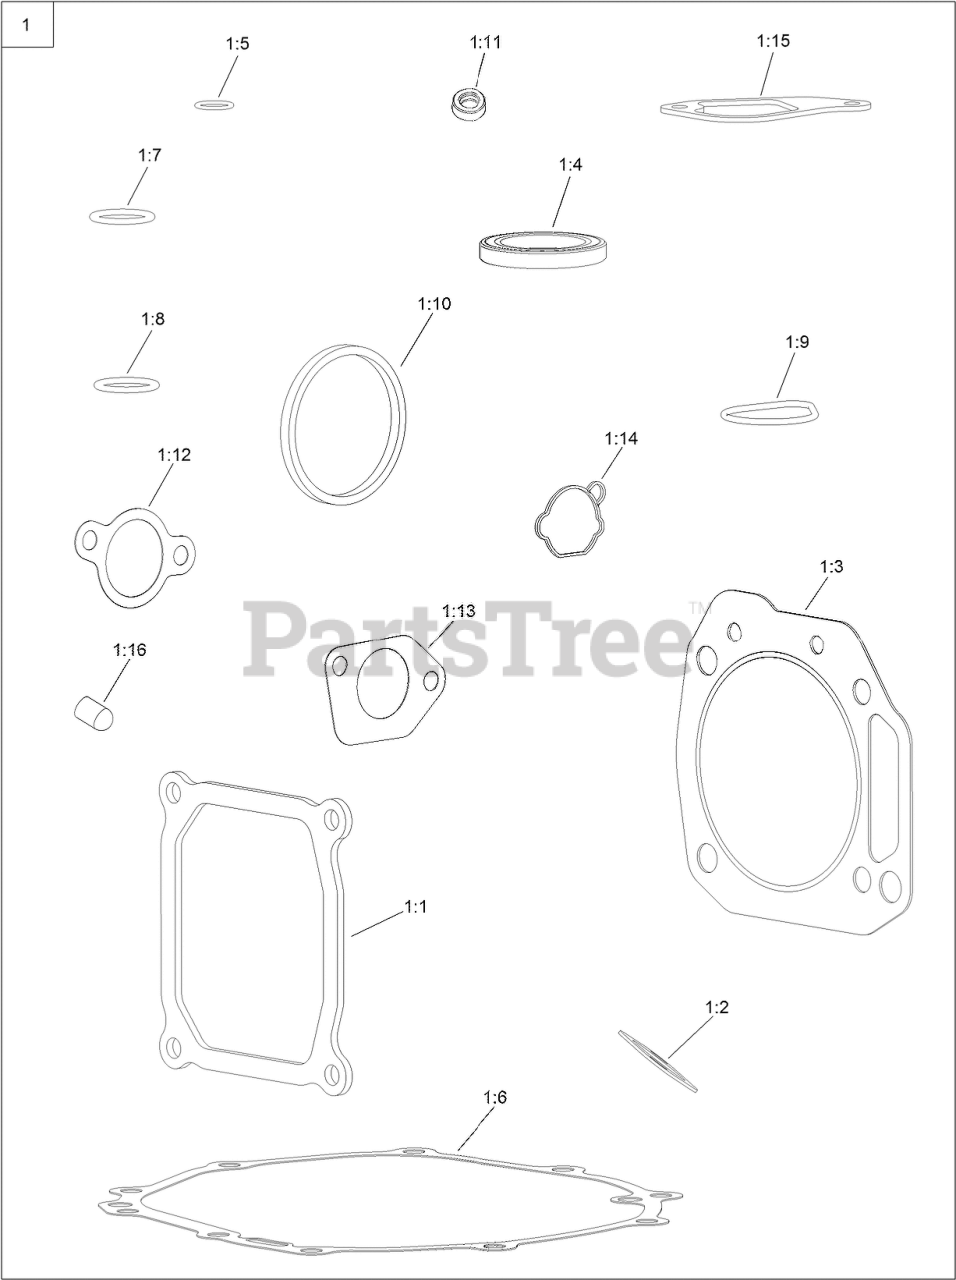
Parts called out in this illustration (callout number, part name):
1	GASKET AND SEAL KIT
1:1	GASKET-COVER, VALVE
1:2	GASKET-EXHAUST
1:3	GASKET-CYCLINDER
1:4	SEAL-OIL
1:5	O-RING
1:6	GASKET-CRANKCASE
1:7	O-RING
1:8	O-RING
1:9	SEAL-PUMP, OIL
1:10	SEAL-ADAPTOR, OIL
1:11	SEAL-OIL
1:12	GASKET-CARBURETOR
1:13	GASKET-CARBURETOR
1:14	GASKET-CARBURETOR
1:15	GASKET-BREATHER
1:16	CAP-SEAL
